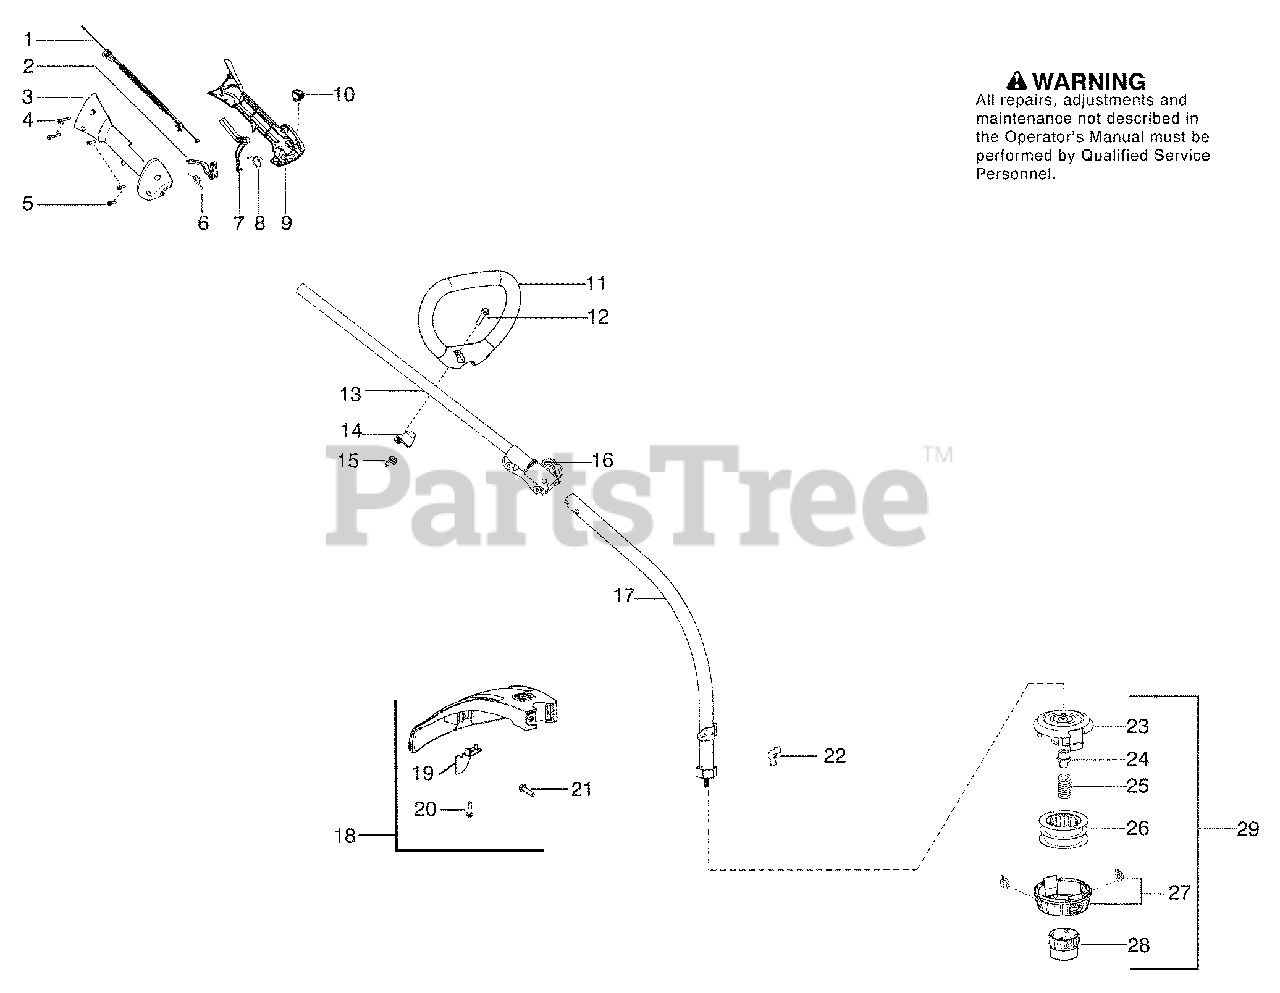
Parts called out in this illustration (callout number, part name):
1	Assy - Cable/Wire Harness
3	Housing - Throttle (RH)
6	Spring - Trigger
7	Lockout - Throttle
8	Spring - Lockout
9	Housing - Throttle (LH)
10	Kit - Switch
11	Handle - Assist
13	Kit - Driveshaft Upper
14	Clamp - Assist Handle
15	Wingnut
17	Kit - Lower Shaft
18	Kit - Shield
19	Limiter - Line
22	Wingnut
26	Assy - Wound Spool
27	Kit Cover and Eyelet
29	Assy. - TNG7 Cutting Head
